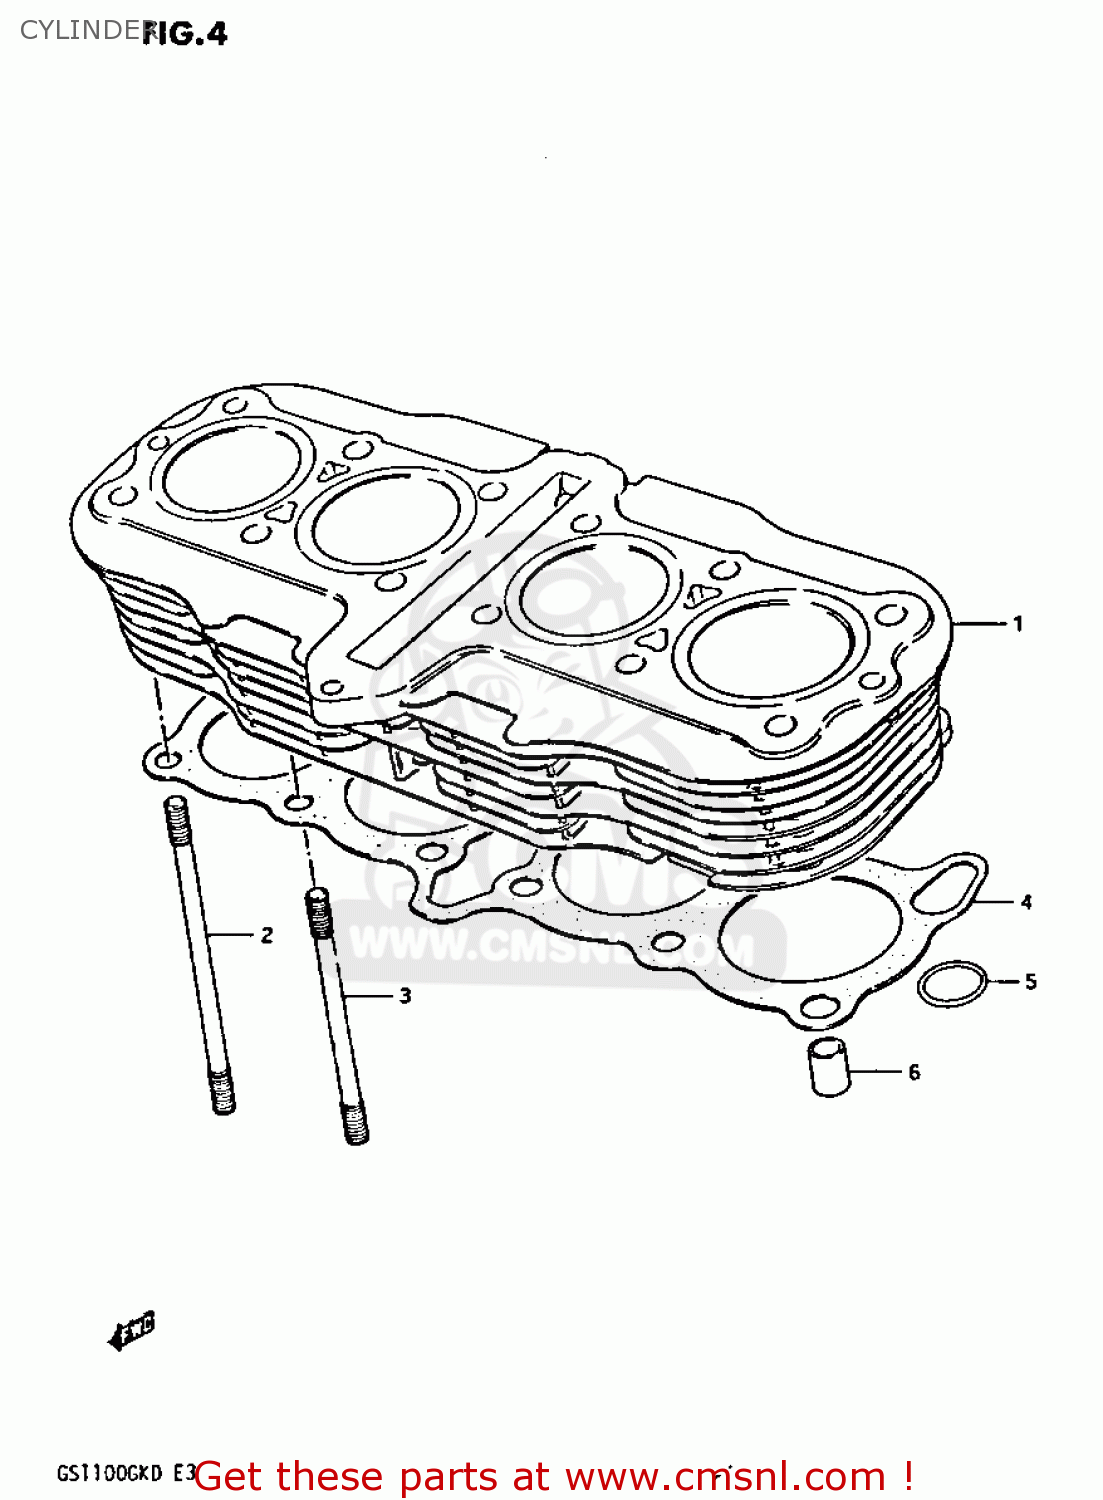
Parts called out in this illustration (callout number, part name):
1	CYLINDER
2	BOLT,STUD
3	BOLT,STUD
4	GASKET,CYLINDER (NAS)
5	O-RING
6	PIN
